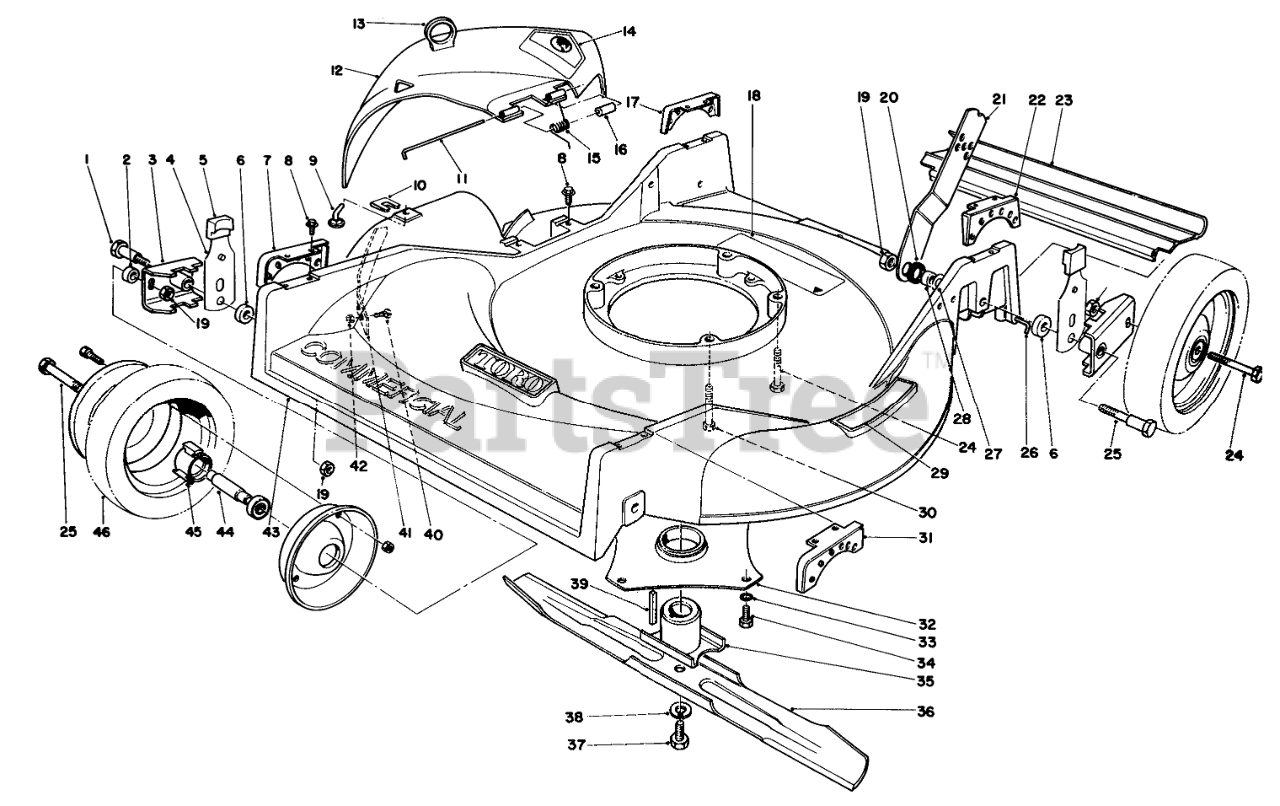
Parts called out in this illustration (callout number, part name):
1	PIVOT SCREW
2	SPACER-WHEEL
3	PIVOT ARM
4	SPRING ARM ASM-FRONT
5	KNOB-ARM
6	SPACER-PIVOT
7	FRT RIGHT QUAD
8	Screw
9	BAG CHUTE PIN
10	BAG CHUTE CLIP PIN
11	DEFLECTOR HINGE PIN
12	Deflector
13	LIFT LOOP
14	DECAL-DANGER
15	DEFLECTOR SPRING
16	SLEEVE
17	REAR RIGHT QUAD
18	DECAL SAF INST
19	NUT-LOCK, NI
20	HANDLE LATCH SPACER
21	Latch-Handle
22	REAR LEFT QUAD
23	SHIELD - TRAILING
24	SCREW-HH
25	REAR PIVOT SCREW
26	SHIELD ROD
27	WASHER-BELLEVILLE
28	HANDLE LATCH SPACER
29	STEP PAD DECAL
30	SCREW-HH
31	FRT LEFT QUAD
32	CRNKSHFT PROTECT ASM
33	WASHER-LOCK, INTERNAL
34	SCREW-HWHTF
35	RETAINER-BLADE
36	Blade
37	SCREW-HH
38	WASHER-LOCK
39	KEY-SQUARE
40	SCREW-CARR
41	Bar-Safety
42	NUT-LOCK, NI
43	Housing
44	BEARING-WHEEL
45	SPACER-BEARING
46	Wheel & Tire Assembly (Incl.Ref. #44 & 45)
